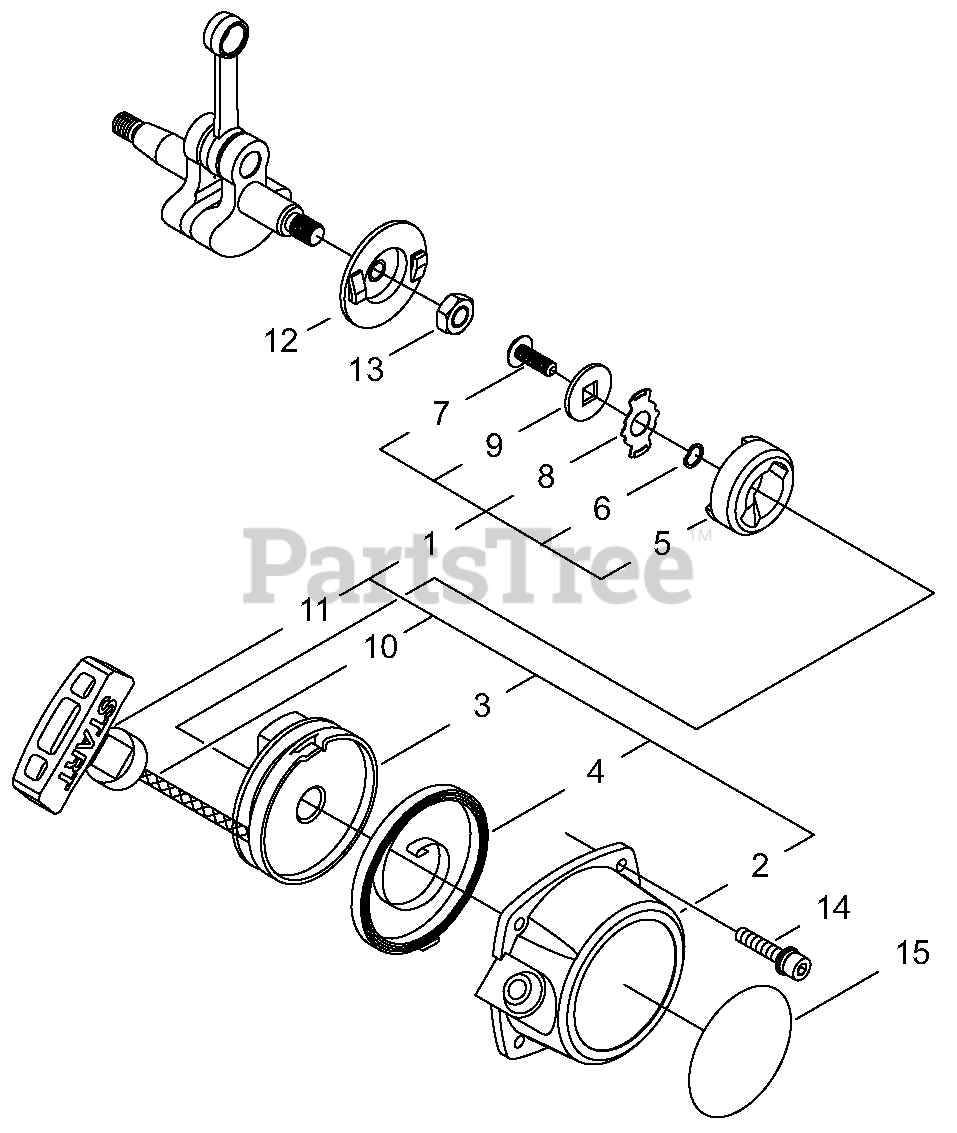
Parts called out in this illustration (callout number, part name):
1	STARTER ASSY, RECOIL
2	CASE, RECOIL STARTER
3	REEL, ROPE
4	SPRING, RECOIL
5	RATCHET
6	WASHER, WAVE
7	SCREW 5 MM
8	RETAINER
9	WASHER 5 MM
10	ROPE, STARTER
11	GRIP, STARTER
12	PULLEY, STARTER
13	NUT M8×1
14	BOLT, ADHESIVE M4×12
15	LABEL, RECOIL STARTER
